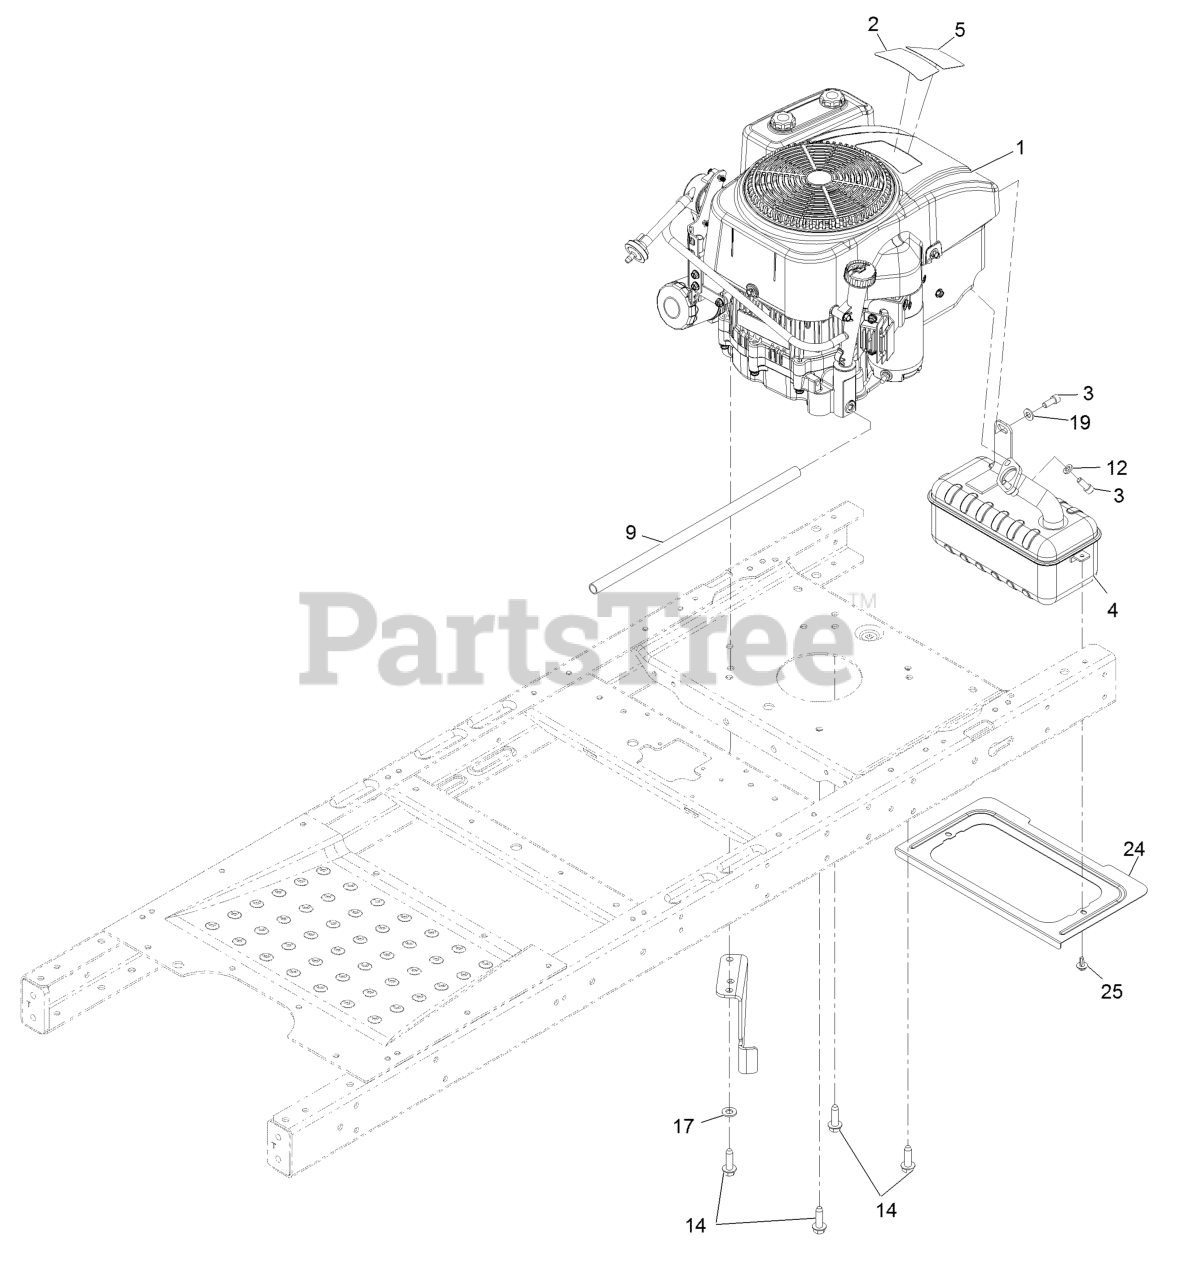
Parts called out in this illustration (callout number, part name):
2	DECAL-ENGINE
3	SCREW-HSH
4	MUFFLER
5	DECAL-ENGINE DISPLACEMENT
9	TUBE-DRAIN, OIL
12	WASHER-LOCK
14	SCREW-THD
17	WASHER-FLAT
19	WASHER-PLAIN
24	SHIELD-HEAT
25	SCREW-HHFTF
